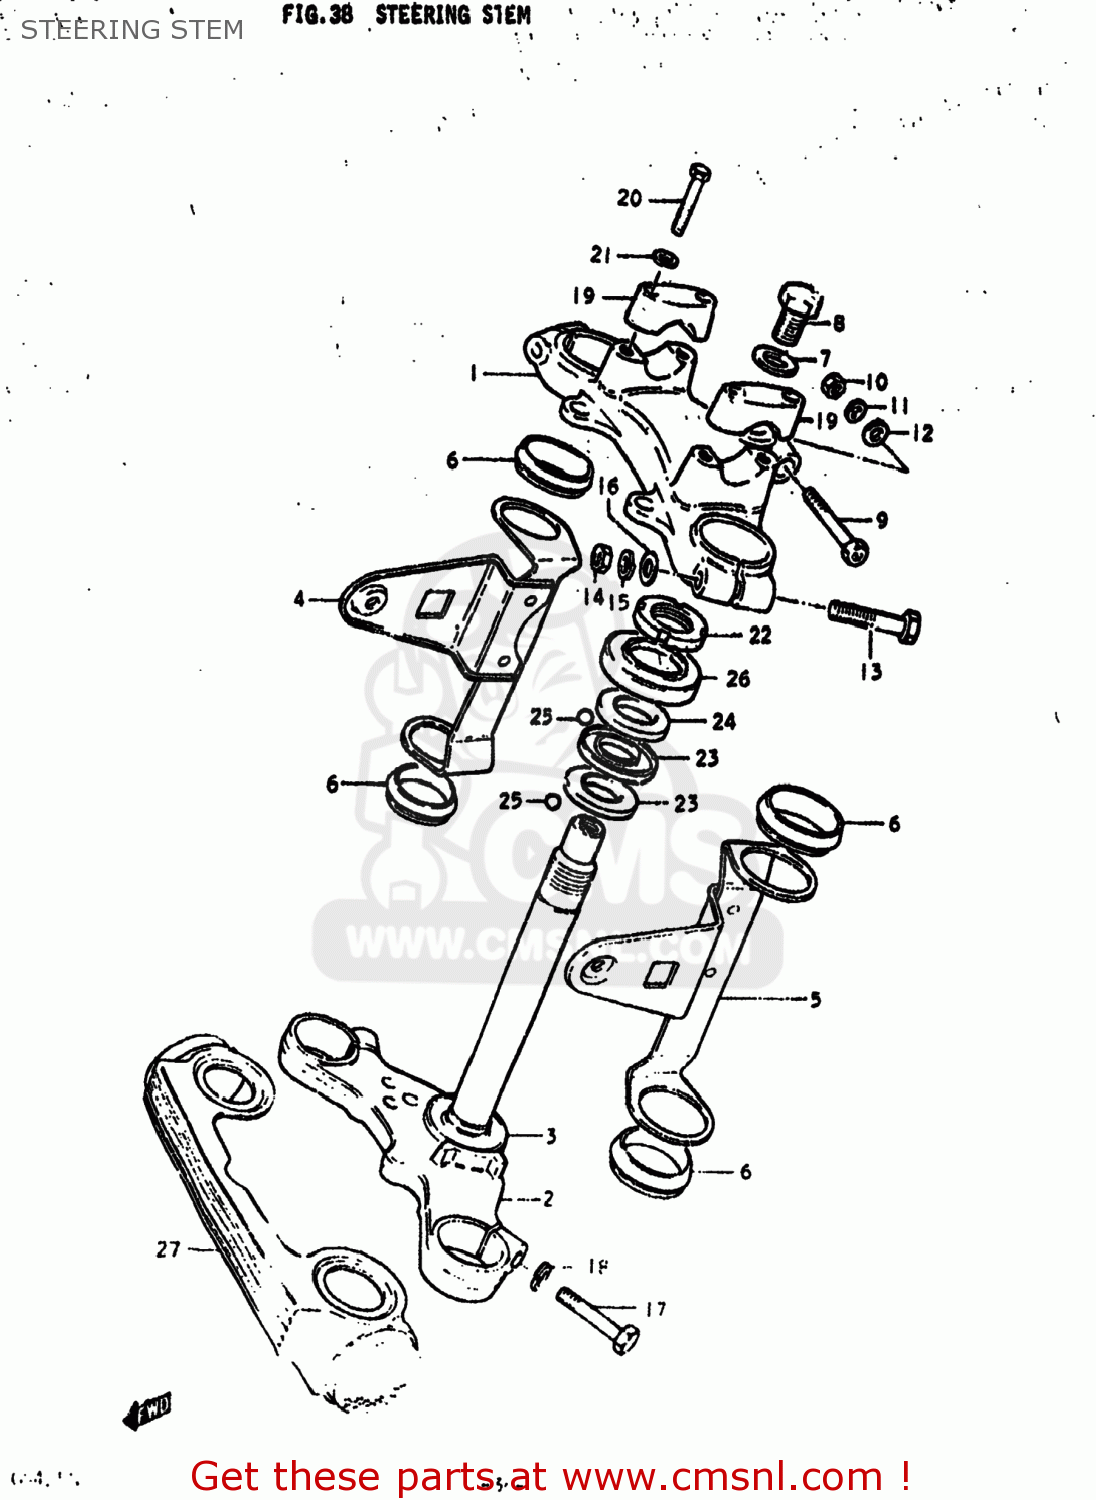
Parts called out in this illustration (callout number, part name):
1	HEAD,STEERING STEM
2	STEM,STEERING
3	RACE,STEERING OUTER LWR
4	BRACKET,HEADLAMP,RIGHT
5	BRACKET,HEADLAMP,LEFT
6	CUSHION,HEADLAMP BRACKET
7	WASHER
8	BOLT(12X20)
9	BOLT
10	NUT
11	LOCK WASHER
12	WASHER
13	BOLT
14	NUT
15	LOCK WASHER
16	WASHER
17	BOLT 10X40
18	LOCK WASHER
19	HOLDER,HANDLE UPR
20	BOLT
21	LOCK WASHER
22	NUT,STEERING STEM(25X44X10)
23	LACE,STEERING INNER LWR
24	LACE,STEERING OUTER UPR
25	BALL
26	DUST SEAL,STEERING UPR
27	COVER,FR FORK
